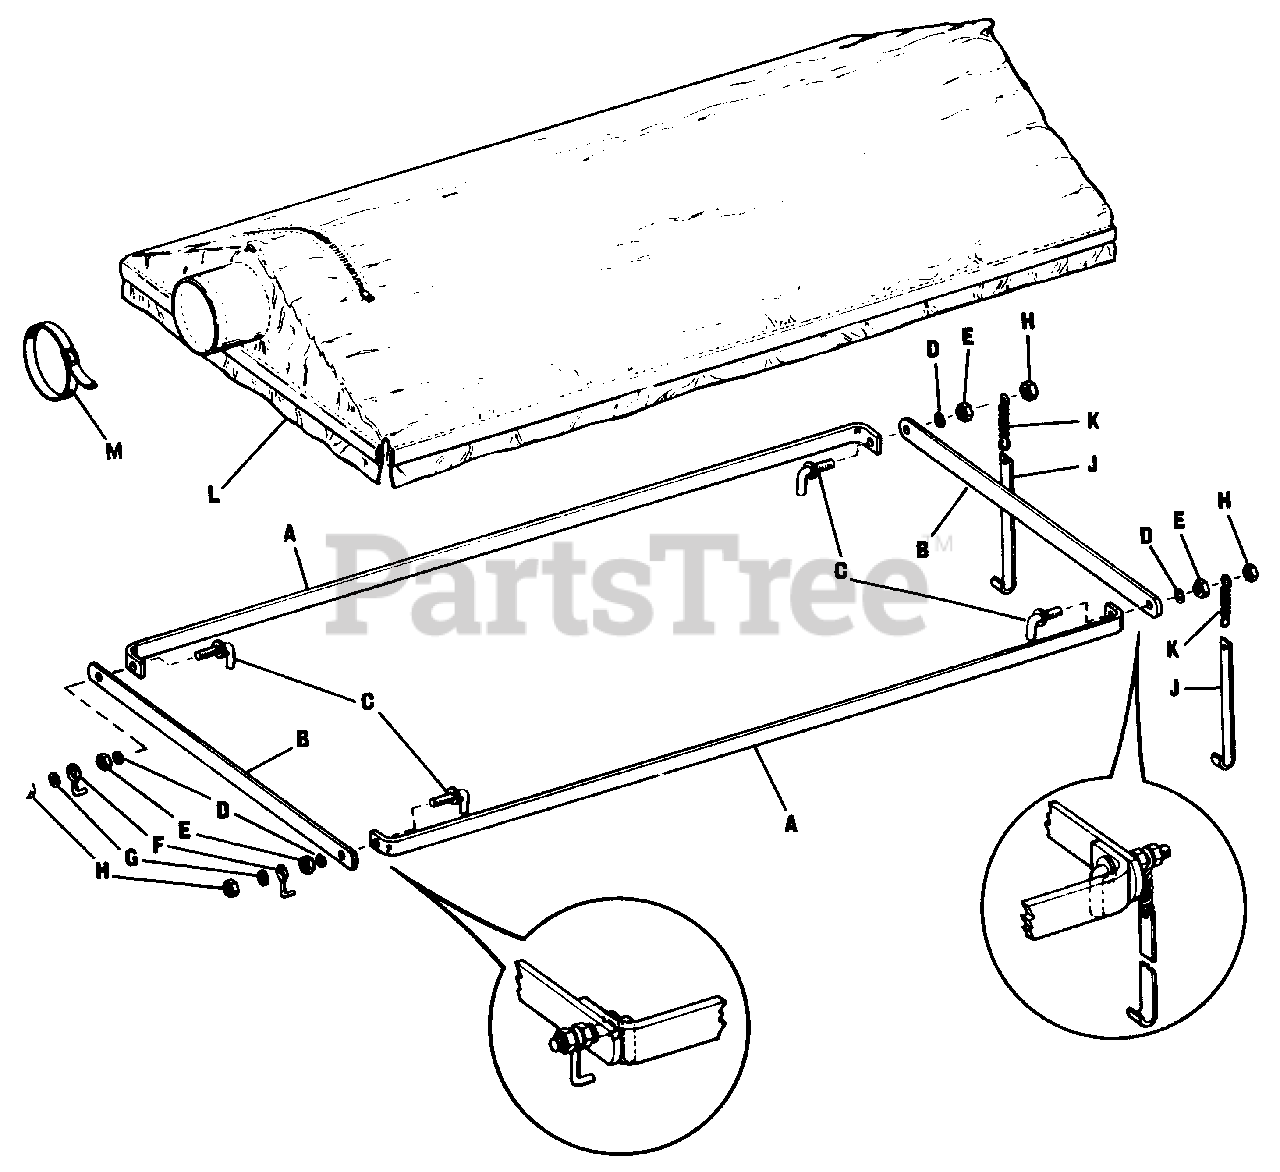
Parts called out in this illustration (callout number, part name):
A	Side Member-Frame
B	End Bracket-Frame
C	Stud Ass'y-Special
D	Washer-Lock-5/16
E	Nut-Hex-Full 5/16"-18NC
G	Washer-Plain 5/16
H	Nut-Hex-Full-Lock 5/16-18NC
J	Hook-Frame-Rear
K	Spring-Rear
L	Cover W/Hose Strap
M	Hose Strap (Service Only)
